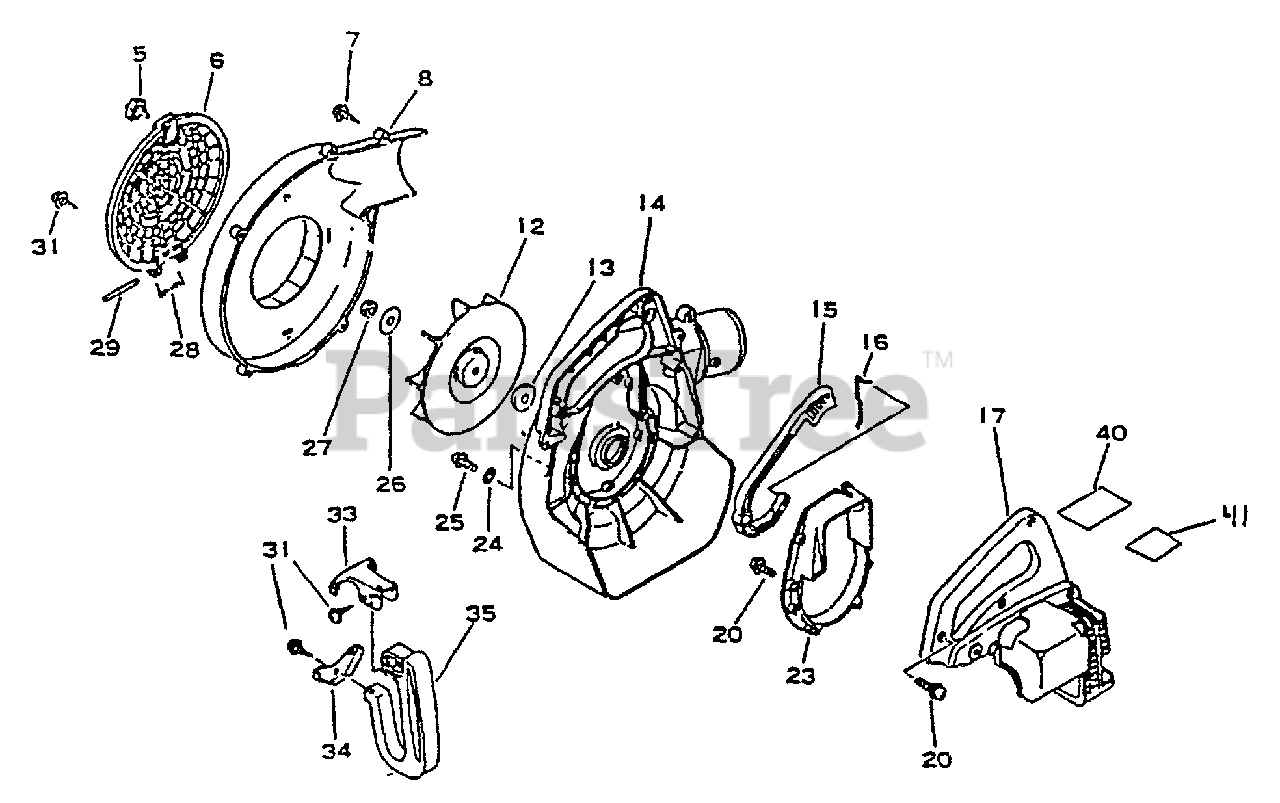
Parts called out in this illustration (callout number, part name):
5	THUMBSCREW
6	GUARD, DEBRIS
7	SCREW - 5X20
8	COVER, FAN - LEFT
12	FAN
13	WASHER - 8
14	COVER, FAN - RIGHT
15	TRIGGER, THROTTLE
16	ROD, THROTTLE
17	COVER, ENGINE
20	SCREW - 4X18
23	BRACKET, ENGINE
25	SCREW - 4X22
26	WASHER
31	SCREW - 5X20
33	BRACKET, HANDLE - UPPER
34	BRACKET, HANDLE - LOWER
35	HANDLE - REAR
40	LABEL - MODEL
41	LABEL - CAUTION
